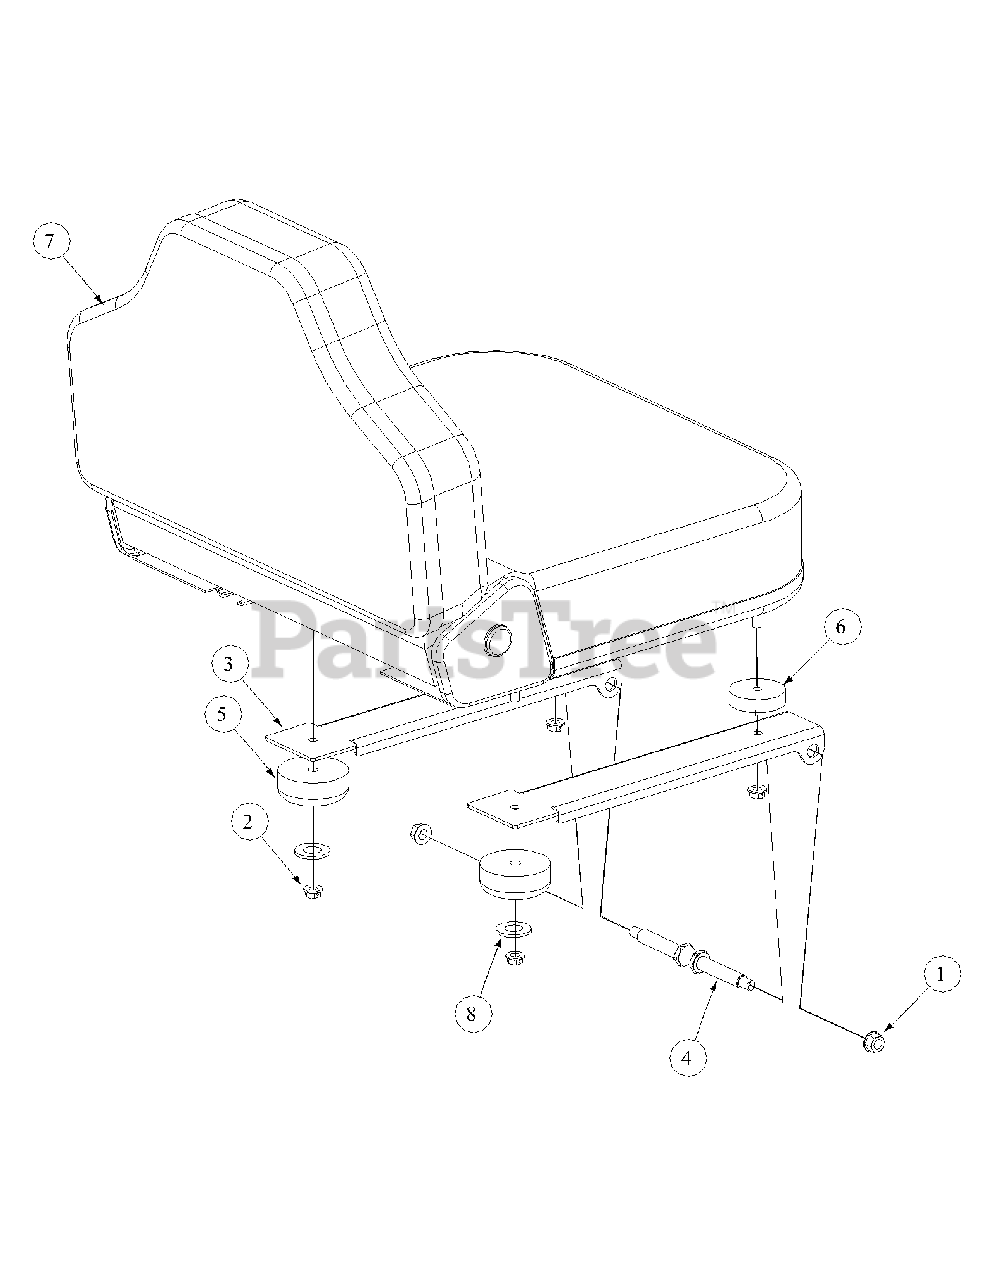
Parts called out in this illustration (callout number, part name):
1	Nut, Hex 3/8-16 Flange Lock
2	Lock Nut, Hex Flange, 5/16-18
3	Mounting Bracket, Seat
4	Shoulder Screw, .50x2.345, 3/8-16
5	Grommet, 2.5 OD x 1.0 Long
6	Spacer,.412 x 1.125 x .44
7	Adjustable Seat, Black
8	Flat Washer, .406 ID, 1.00 OD, .105
